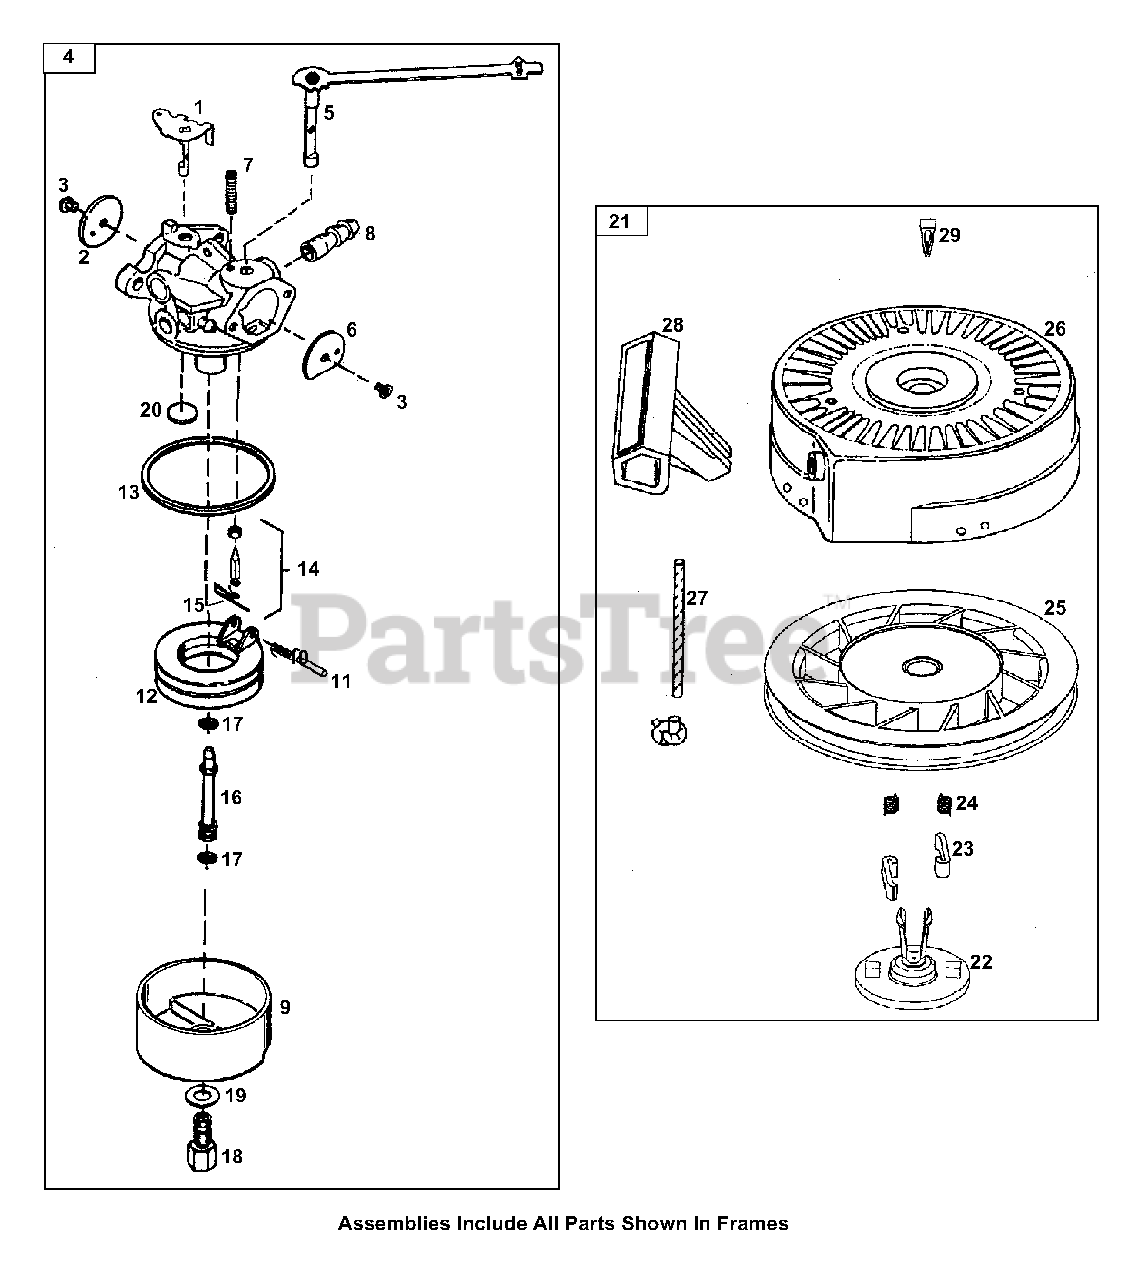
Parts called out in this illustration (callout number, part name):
1	Throttle Shaft & Lever Ass'y
2	Throttle Shutter
3	Shutter Screw
4	Carburetor Assembly
5	Choke Shaft & Lever Ass'y
6	Choke Shutter
7	Choke Positioning Spring
8	Fuel Fitting
9	Float Bowl
10	Float Dampening Screw
11	Float Shaft
12	Float
13	Float Bowl O-Ring
14	Inlet Needle, Seat & Clip
15	Spring Clip
16	Main Nozzle Tube
17	O-Ring Main Nozzle Tube
18	High Speed Bowl Nut
19	Bowl Nut Washer
20	Welch Plug, Atmospheric Vent
21	Rewind Starter Ass'y
23	Starter Dog
24	Dog Spring
25	Pulley Ass'y
26	Starter Housing Ass'y
27	Starter Rope (98")
28	Starter Handle
29	Locking Tab
